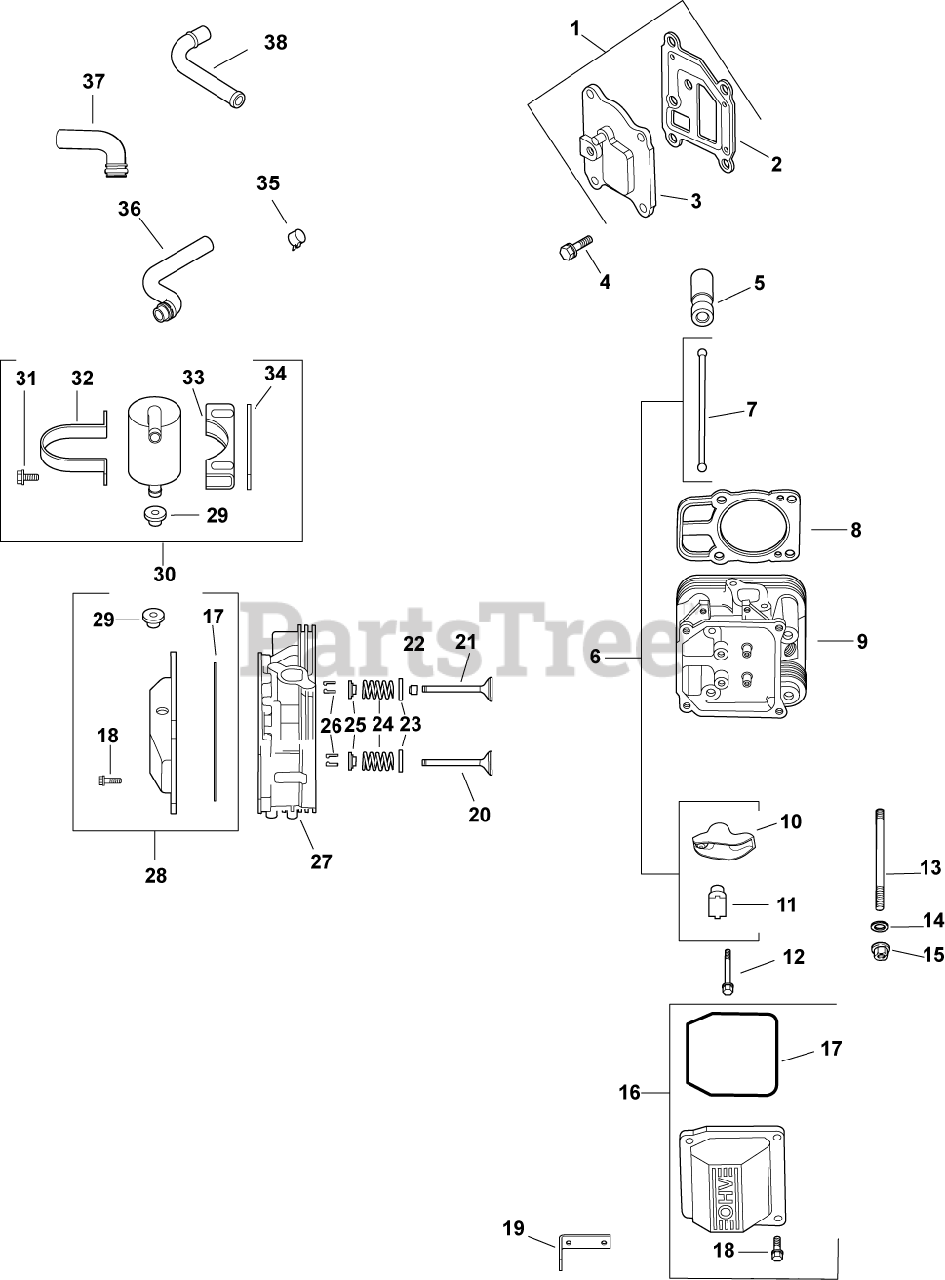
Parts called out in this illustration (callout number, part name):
1	KIT, BREATHER COVER W/GASKET
2	GASKET, BREATHER-USE 24 041 67-S
3	COVER, BREATHER -USE 24 096 125-S
4	SCREW,FLG THD FRM M6X1.0X20-(#25086396S)
5	LIFTER, HYDRAULIC VALVE-USE 25 351 10-S
6	KIT, VALVE TRAIN
7	ROD, PUSH
8	KIT, GSKT CYL HD (C22-23 674CC)
9	KIT, CYLINDER HEAD #2
10	ARM, ROCKER
11	PIVOT, ROCKER ARM
12	SCREW, FLG M6X1.0X34
13	STUD, M8X1.25
14	WASHER, FLAT 8.6 MM
15	NUT, FLG M8X1.25
16	KIT, VALVE COVER-PLAIN
17	O-RING (YELLOW), VALVE COVER
18	SCREW, FLG M6X1.0X30
19	STRAP, LIFTING-USE 25 445 03-S
20	VALVE, EXHAUST (STD) - USE 32 016 01-S
21	VALVE, INTAKE (STD)
22	SEAL, VALVE STEM - (#2503214S)
23	RETAINER, SPRING
24	SPRING, VALVE
25	RETAINER, VALVE SPRING - USE 25 173 28-S
26	KIT, RETAINER
27	KIT, CYLINDER HEAD #1
28	KIT, VALVE COVER
29	GROMMET, RUBBER
30	KIT, BREATHR SEPARATR-(#24755241S)
31	SCREW,FLG THD FRM M5X0.8X16-(#25086398S)
32	STRAP, BREATHER - USE 24 755 241-S
33	BRACKET, BREATHER SEPARATOR
34	SPACER
35	CLAMP, HOSE (KM)-USE 25 237 31-S
36	HOSE, BREATHER
38	HOSE, BREATHER
2401602-S	VALVE, EXHAUST (.25)
2401702-S	VALVE, INTAKE (.25)
